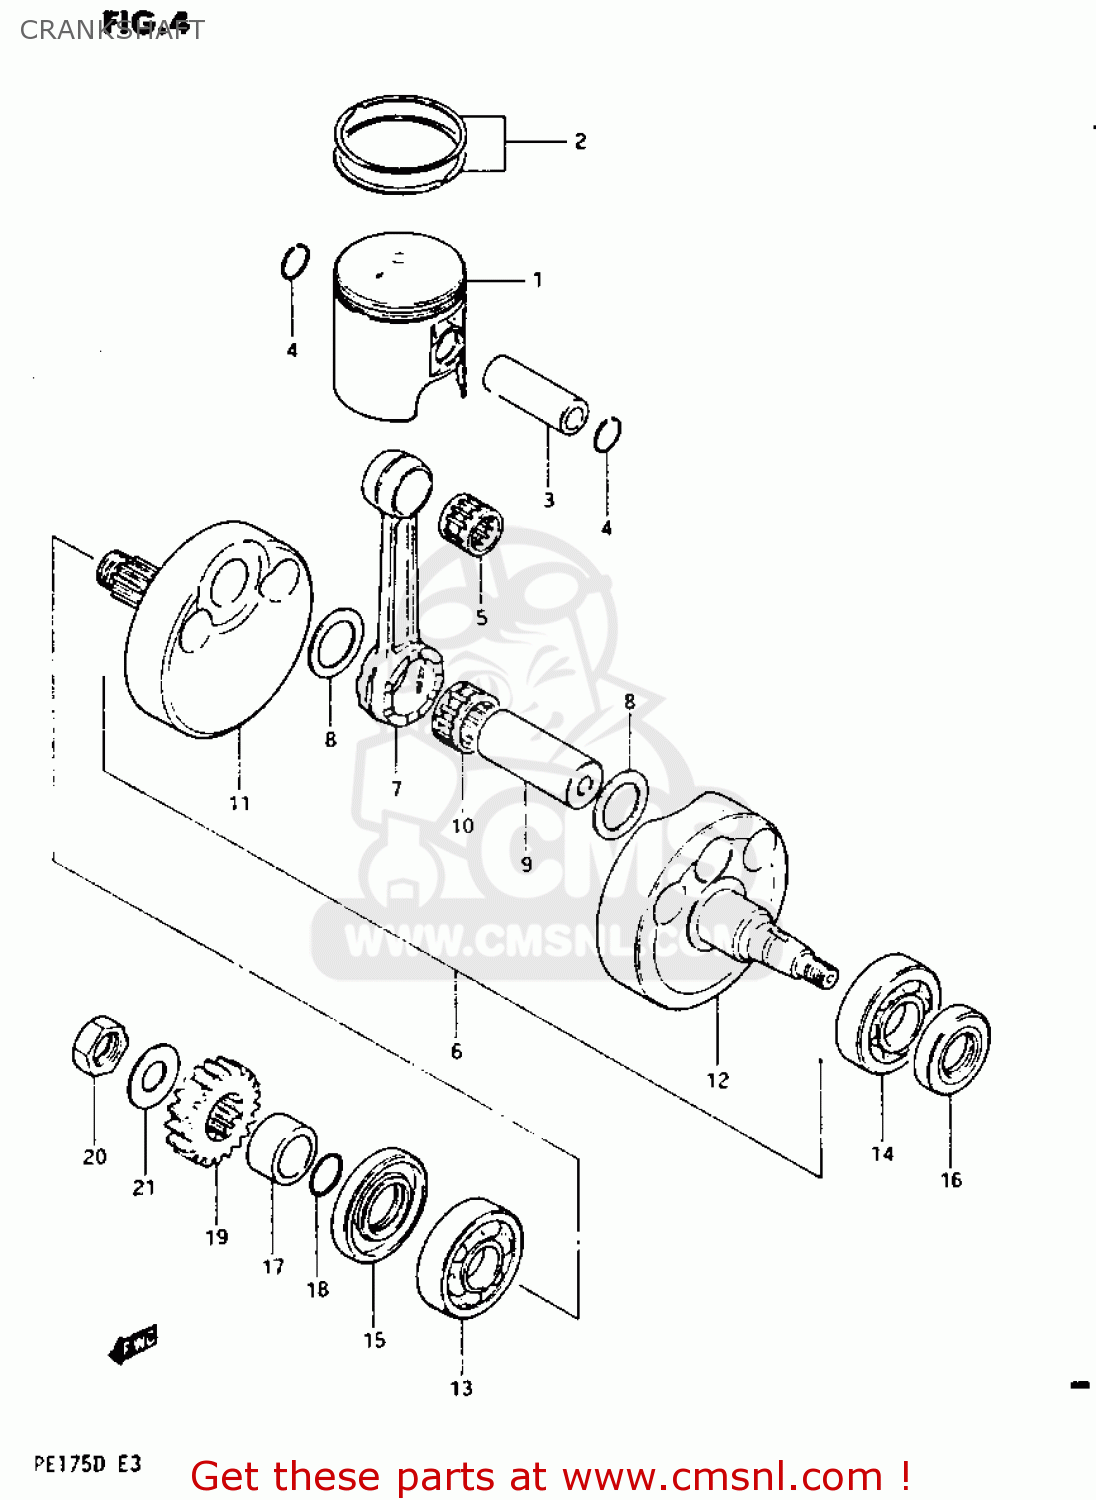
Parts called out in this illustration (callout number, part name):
1	PISTON
2	RING SET,PISTON
3	PIN,PISTON
4	RING,SNAP 16MM
5	BEARING
6	CRANKSHAFT ASSEMBLY
7	ROD,CONNECTING
8	WASHER(22X35X1)
9	PIN,CRANK
10	BEARING(22X28X16)
11	CRANKSHAFT
12	CRANKSHAFT,LEFT
13	BEARING(22X56X16)
14	BEARING(25X52X15)
15	SEAL,OIL(29X47X8)
16	SEAL,OIL(25X44X7)
17	SPACER
18	O RING(D:2.4,ID:19.8)
19	GEAR,PRIMARY DRIVE
20	NUT
21	WASHER
